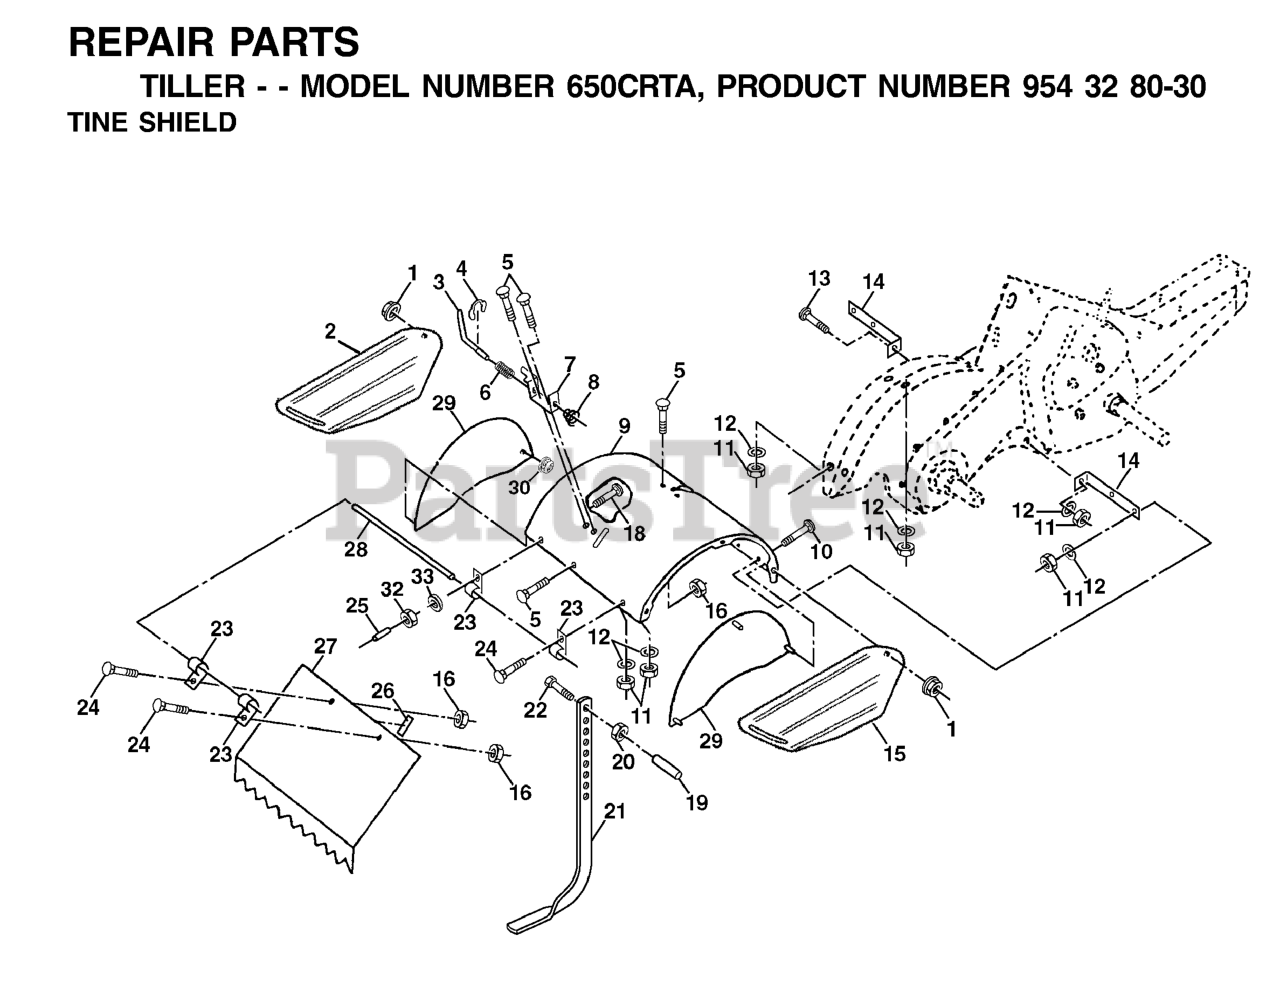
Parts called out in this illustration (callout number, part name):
1	NUT LOCK HEX FLANGE 5/16-18
2	SHIELD
3	STAKE PIN TI
4	KLIP RING TI
5	RP BOLT 5/16-18 X3/4 ZN/YEL GR
7	BRACKET.LATCH.STAKE.3.20.BLACK
8	SPRING CRT
9	SHIELD
10	BOLT
11	NUT
12	WASHER.LOCK.HVY.HLCL.SPR.5/16
13	BOLT.CARRIAGE.5/16-18
14	BRACKET.TINE.SHIELD.TILLER.BLA
15	SIDE SHIELD RH
16	NUT T
20	NUT.HEX.3/8-16UNC
21	STAKE.DEPTH.16.CRT.BLACK
22	BOLT.375-16
24	BOLT
25	VINYL CAP TI
26	PAD IDLER TI
27	SHIELD LEVELING
28	PIN.HINGE.TILLER
29	SIDE SHIELD
30	LOCKNUT-FLANGE 5/16-18
32	NUT
33	LOCKWASHER
